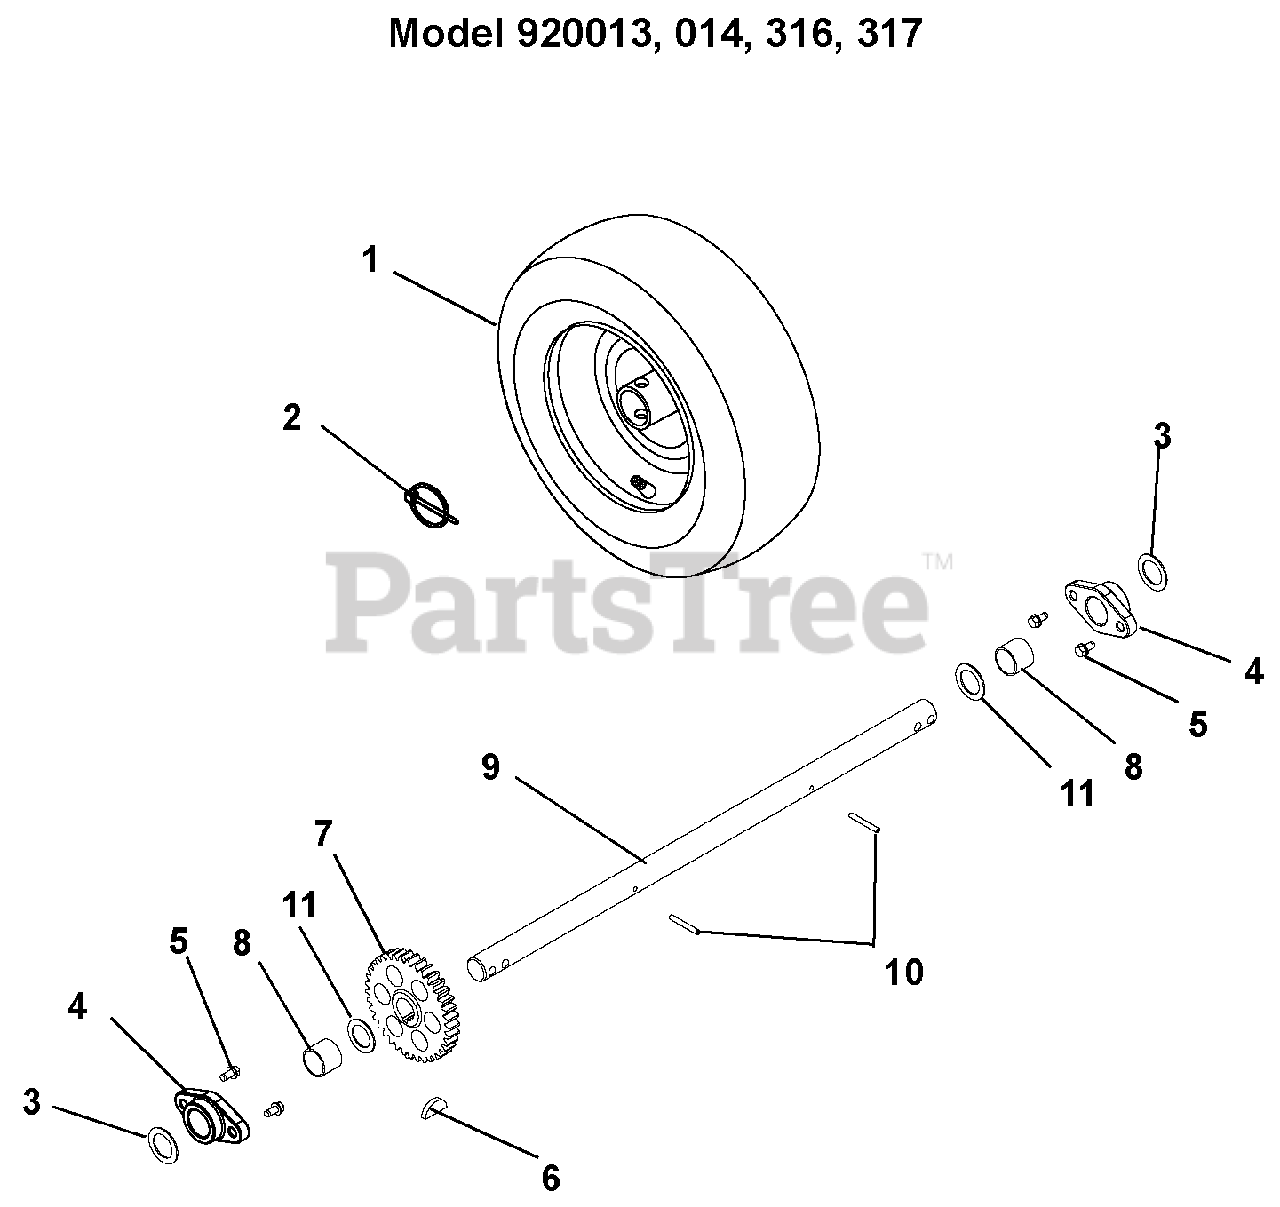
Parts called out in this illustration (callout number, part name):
1	TIRE/WHEEL, 13X4.10-6 K398A
2	PIN-LOK .31X1.75
3	WSHR-FL-STL.754X1.125X.062YWZC
4	BSHG .75X1.125X.65
5	SCR-TAP .25-20X.50 HWH TR YWZ
6	KEY-WDRF .25X.750X.313 SAE91
7	SPUR GEAR, 54T .75ID X 6.75PD
8	BSHG-SLV .766 X 1.125 X .500
9	SHAFT, AXLE
10	PIN-ROLL .188X1.25
11	WSHR-FL-STL.754X1.125X.062YWZC
